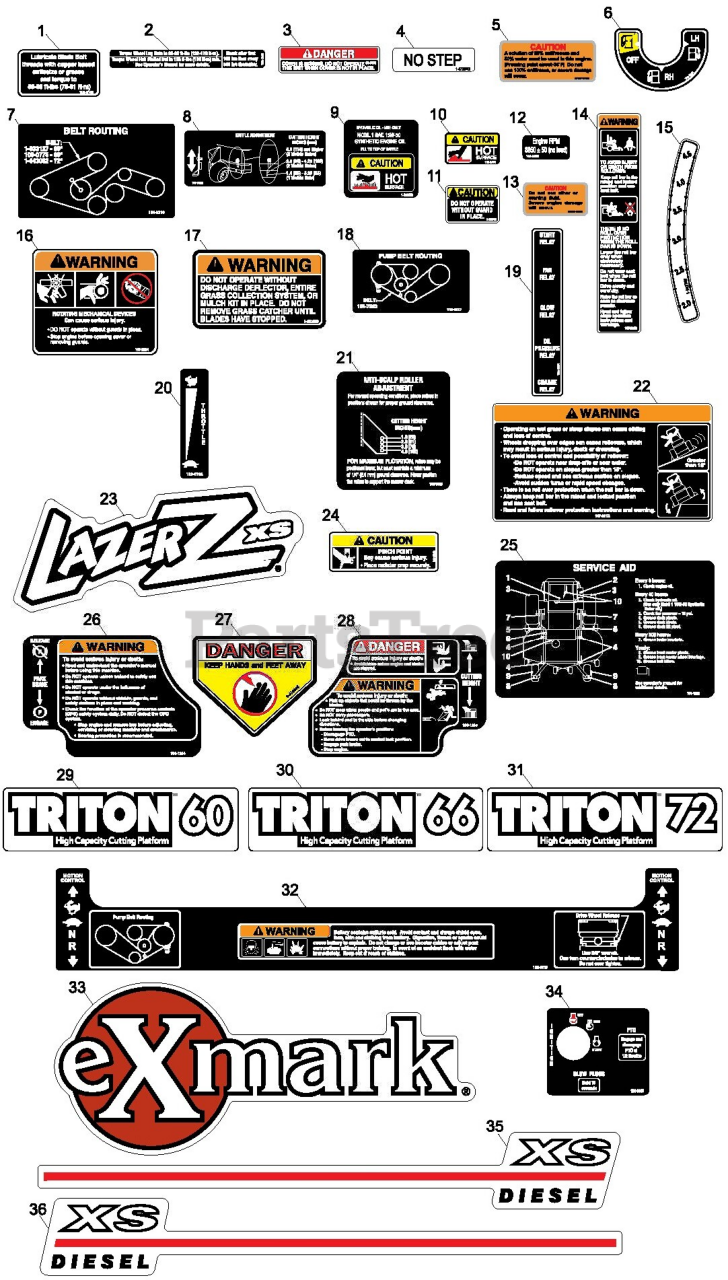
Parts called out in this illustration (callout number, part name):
1	DECAL,BOLT TORQUE
3	DECAL-COVER, MISSING
4	DECAL,NO STEP
5	DECAL-ANTIFREEZE
6	DECAL-VALVE, FUEL
7	DECAL,BELT ROUTING
8	DECAL,BAFFLE ADJUSTMENT
10	DECAL-CAUTION
11	DECAL-GUARD
13	DECAL-CAUTION
14	DECAL-WARNING, FOLDING RO
15	DECAL-HEIGHT, DECK
16	DECAL,WARNING
17	DECAL-WARNING, DISCHARGE
18	DECAL,HYDRO BELT ROUTING
19	DECAL,RELAY KUBOTA
20	DECAL,THROTTLE ONLY
21	DECAL,ANTISCALP
22	DECAL-WARNING
23	DECAL,LAZER XS MODEL
24	DECAL,RADIATOR ASSEMBLY
25	DECAL,SERVICE AID
26	DECAL,PARK BRAKE
27	DECAL-DANGER
28	DECAL,DECK HEIGHT
29	DECAL,TRITON 60
30	DECAL,TRITON 66
31	DECAL,TRITON 72
32	DECAL-CONSOLE, TOP
33	DECAL,EXMARK
34	DECAL,IGNITION,GLOW,PTO
35	DECAL,HOOD LXS DIESEL RH
36	DECAL,HOOD LXS DIESEL LH
